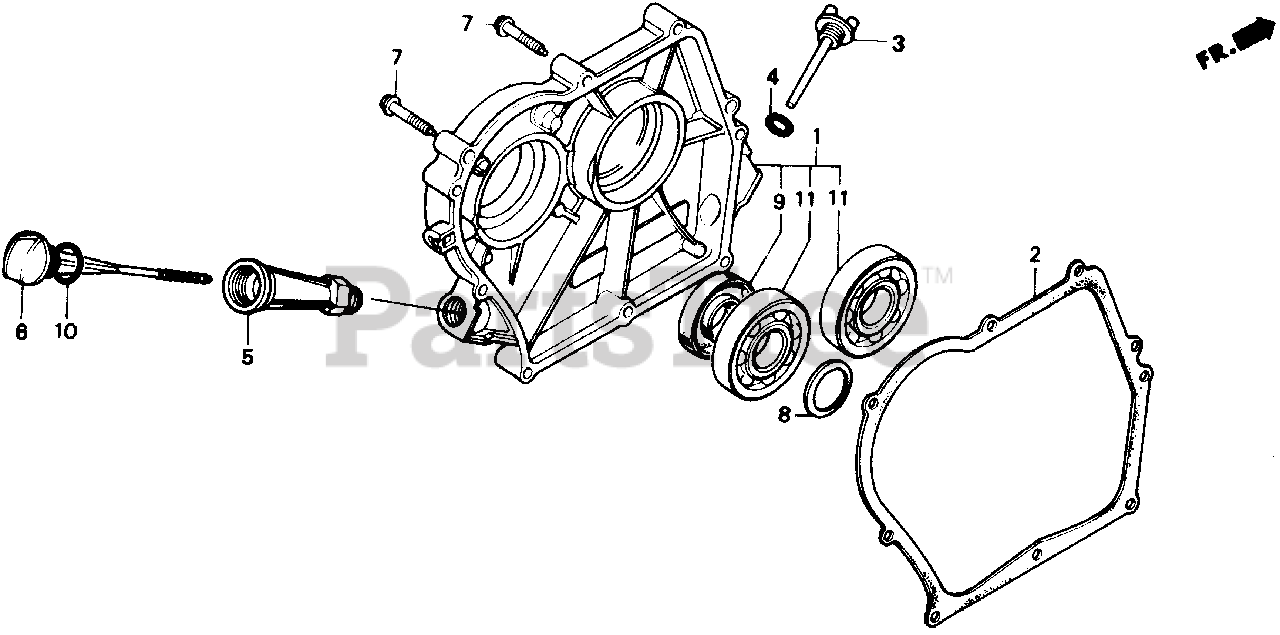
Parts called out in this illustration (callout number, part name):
1	COVER ASSY., CRANKCASE (L-TYPE)
2	GASKET, COVER
4	GASKET, OIL FILLER CAP
5	PIPE, OIL FILLER
6	DIPSTICK, OIL
7	BOLT, FLANGE (6X32)
8	WASHER, THRUST SPRING
9	OIL SEAL (25X41X6)
10	O-RING (23X2.8)
11	BEARING, RADIAL BALL (6205)
